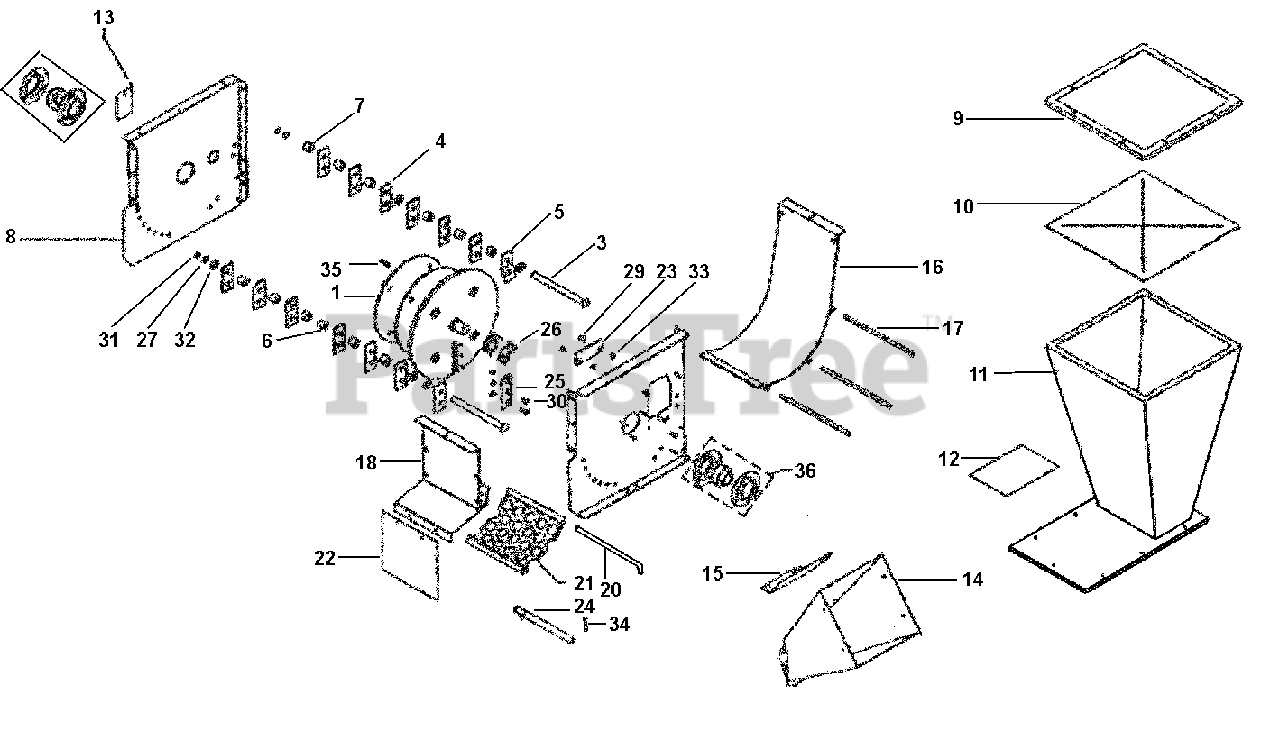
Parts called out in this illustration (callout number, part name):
3	SHAFT, HAMMER
4	HAMMER, STRAIGHT
5	HAMMER, L-SHAPED
9	DEFLECTOR SUPPORT
10	HOPPER FLAP
13	Cover Inspection
14	CHIPPER CHUTE
15	SUPPORT PLATE, CHUTE
16	PANEL, BOTTOM
18	DISCHARGE DEFLECTOR
23	BLADE, STATIONARY
36	BEARING ASSEMBLY
NI	ROTOR COMPLETE
